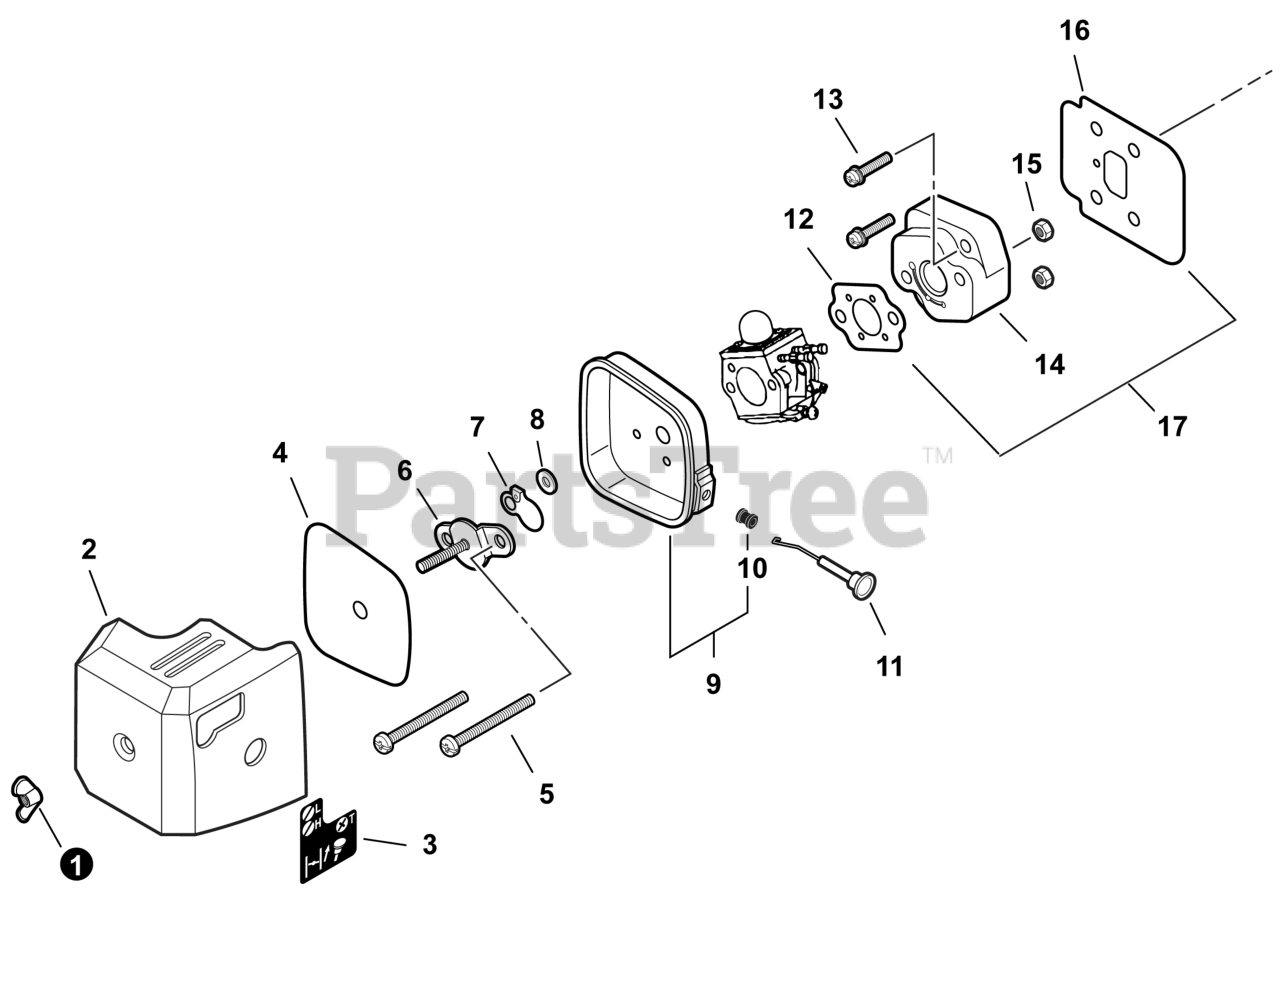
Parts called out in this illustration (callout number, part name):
1	WINGNUT - 6
2	COVER, AIR FILTER
3	LABEL - CHOKE
4	FILTER, AIR
5	SCREW 5x57
6	PLATE, PREVENT
7	SHUTTER, CHOKE
8	WASHER 5.2x8x0.8T
9	CASE, AIR FILTER
10	GROMMET, CHOKE
11	ROD, CHOKE
12	GASKET, INTAKE
13	SCREW 5x20
14	INSULATOR, INTAKE
16	HEAT SHIELD, INTAKE
17	GASKET KIT: ENGINE, INTAKE, EXHAUST
